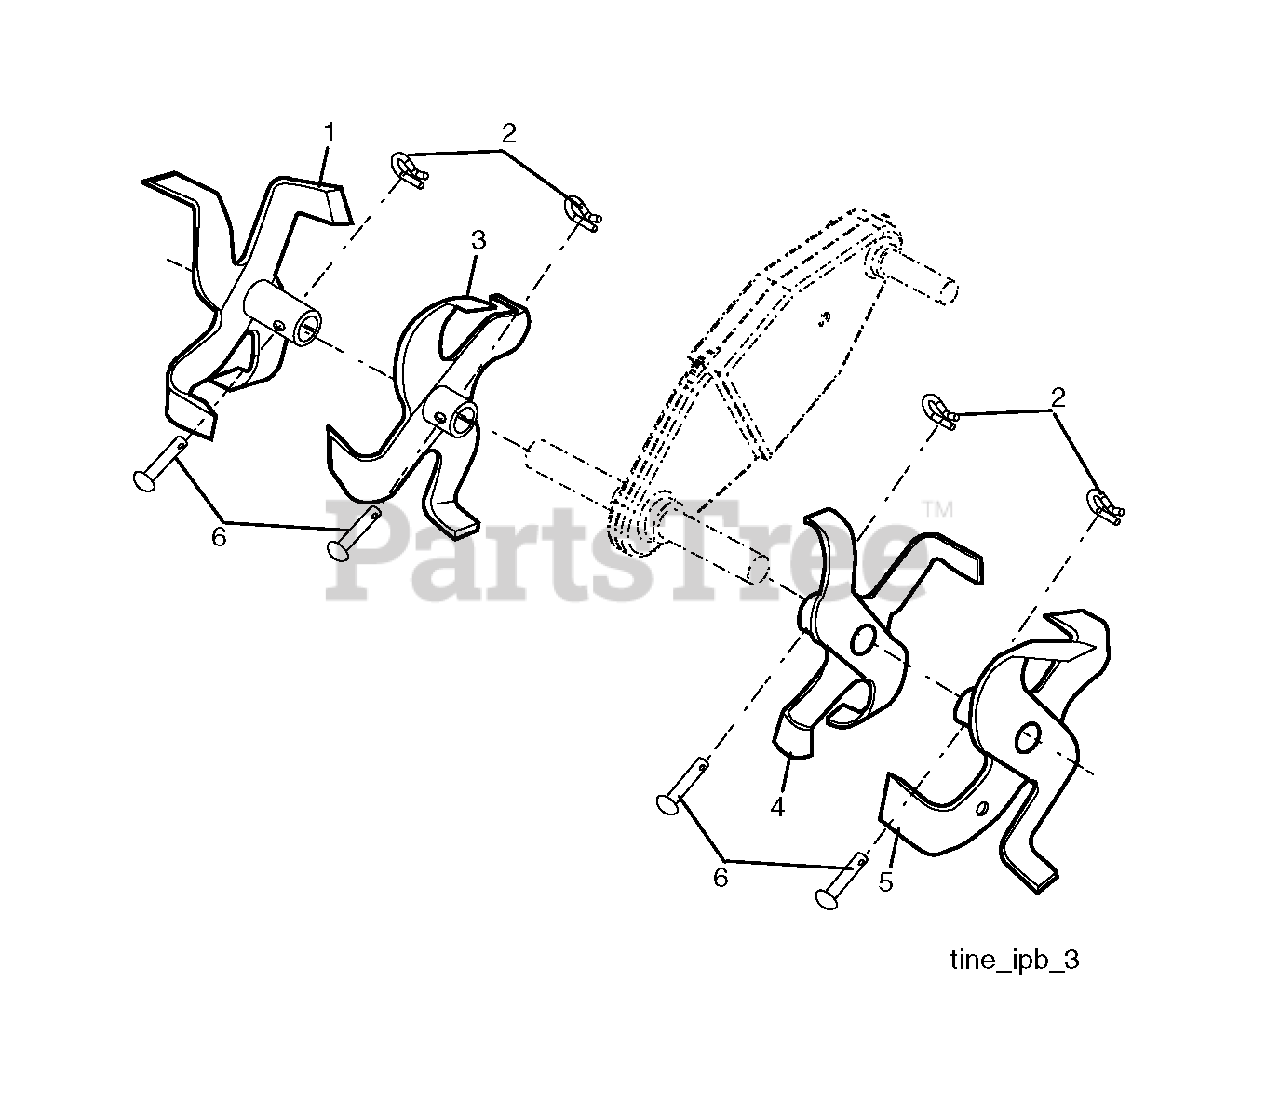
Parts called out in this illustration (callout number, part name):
1	RP TINE
3	RP TINE
4	RP TINE
5	RP TINE
6	RIVET TI
